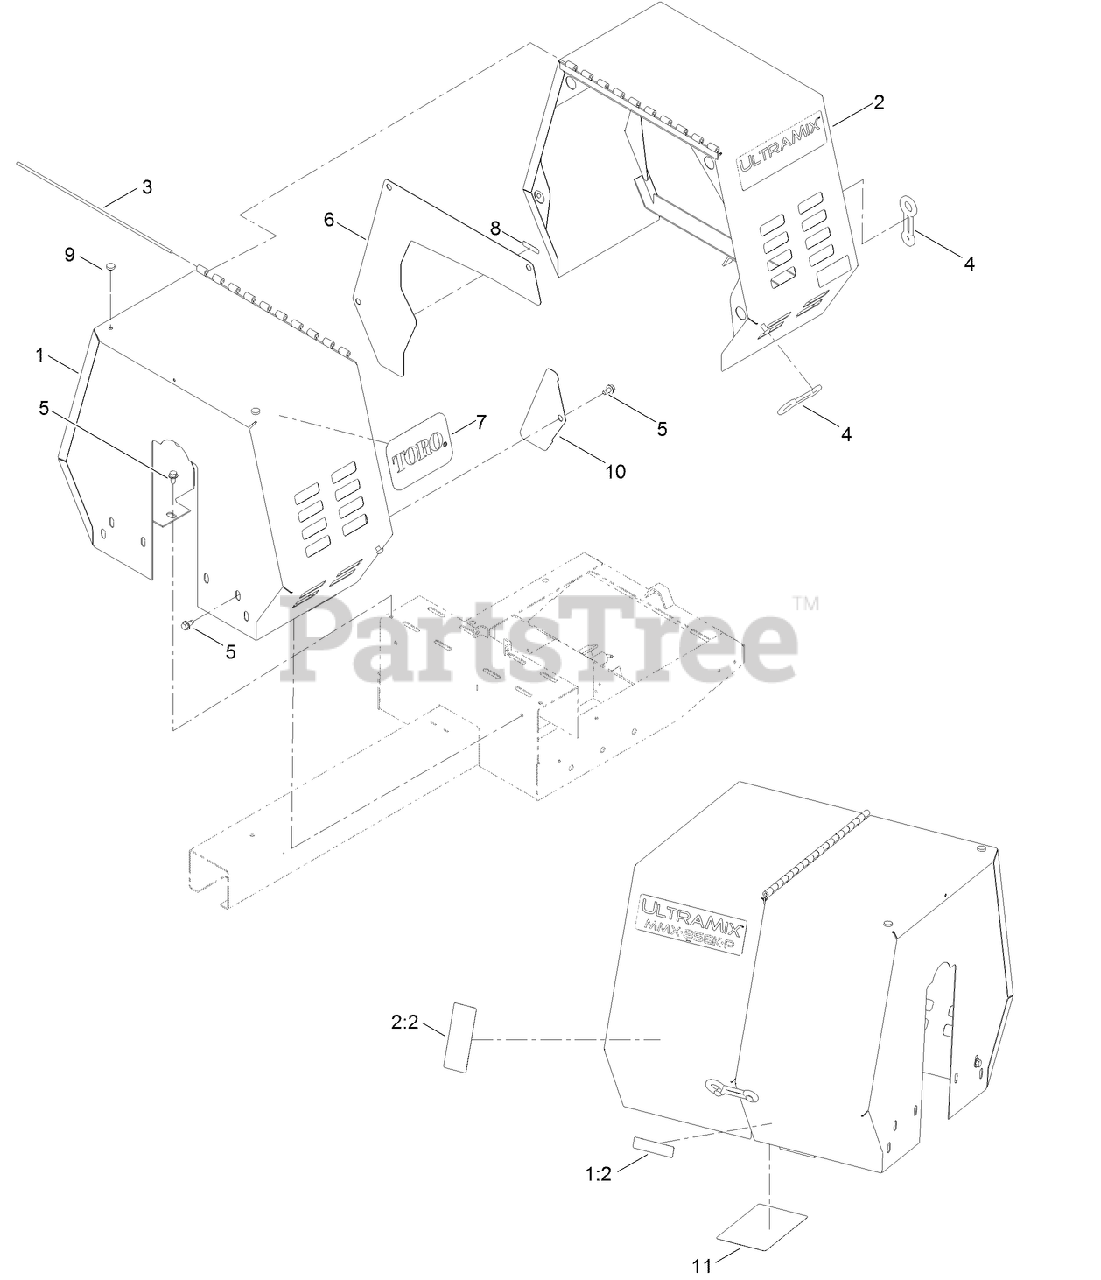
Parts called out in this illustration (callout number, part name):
1	STATIONARY COWL ASM
1:2	DECAL-ARRESTOR, SPARK
2	MOVABLE COWL ASM
2:2	DECAL-WARNING
4	LATCH-RUBBER
5	SCREW-HWH
6	PLATE-ACCESS, BELT
7	DECAL
8	DECAL-GREASE
9	BUMPER
10	PLATE-ACCESS, BELT
11	DECAL-SERVICE
